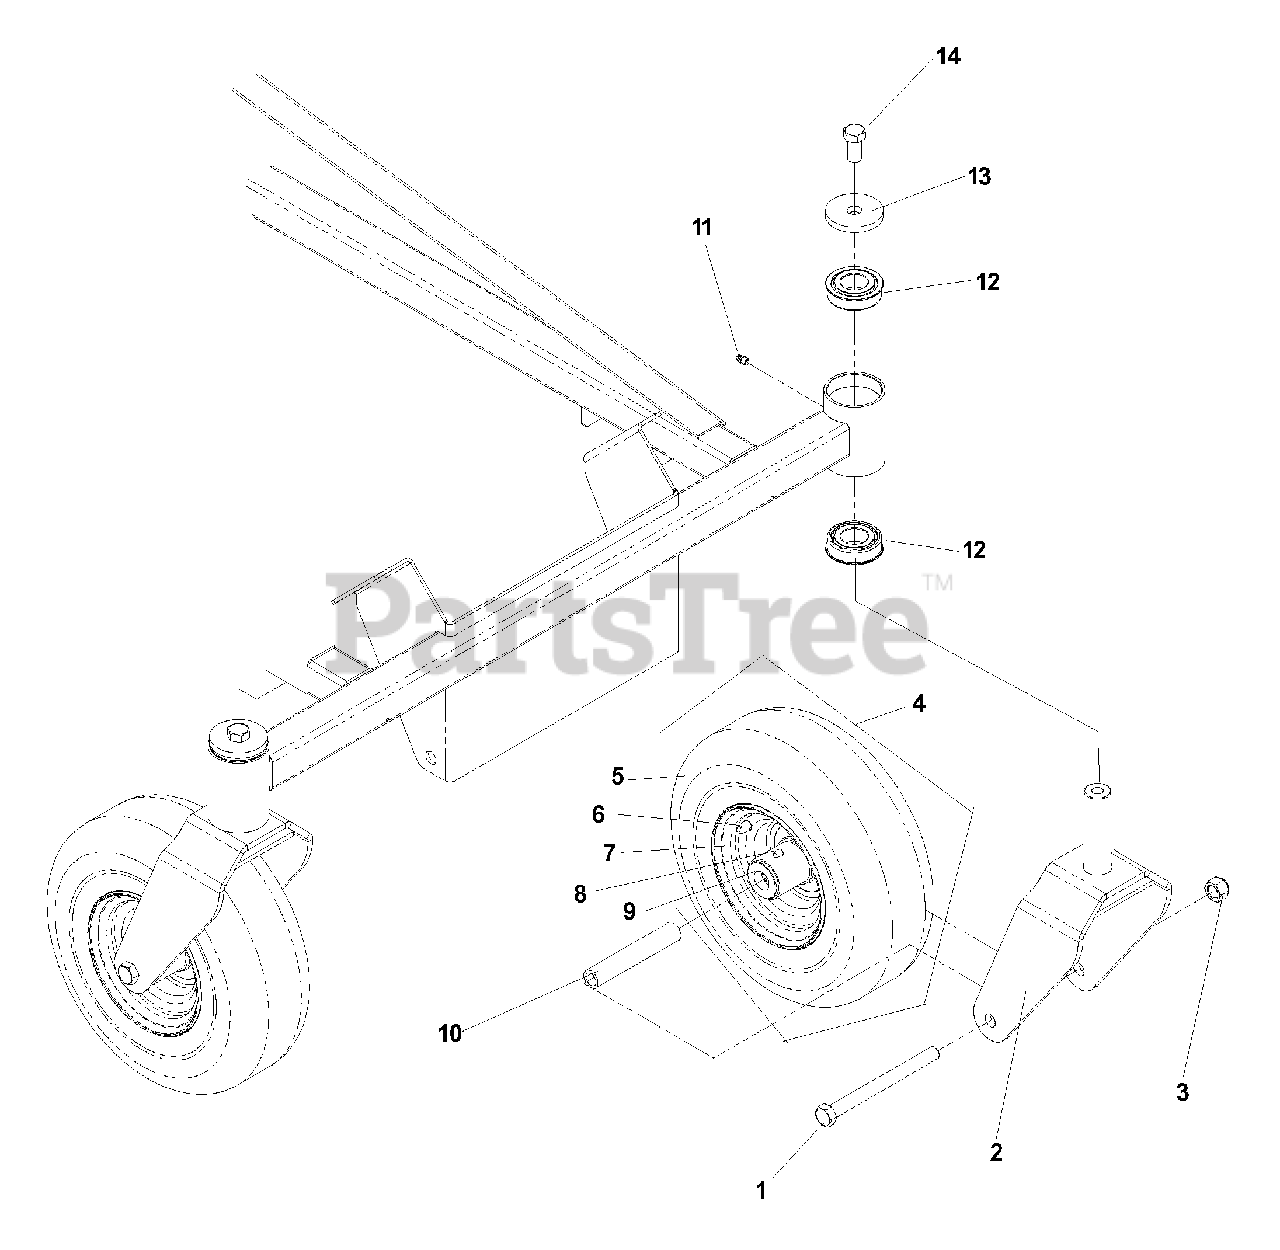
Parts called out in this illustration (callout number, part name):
1	HCS, 1/2-13 X 5 1/2, GR5
2	CASTER YOKE
3	NUT, 1/2-13, NYLOC
4	CASTER TIRE, COMPLETE
5	TIRE, 4 PLY, 410/350-5
6	VALVE STEM
8	ZERK
9	BEARING, FLANGED
12	BEARING, FLANGED
13	HEAVY WASHER
14	HCS, 1/2-13 X 1, GR5
